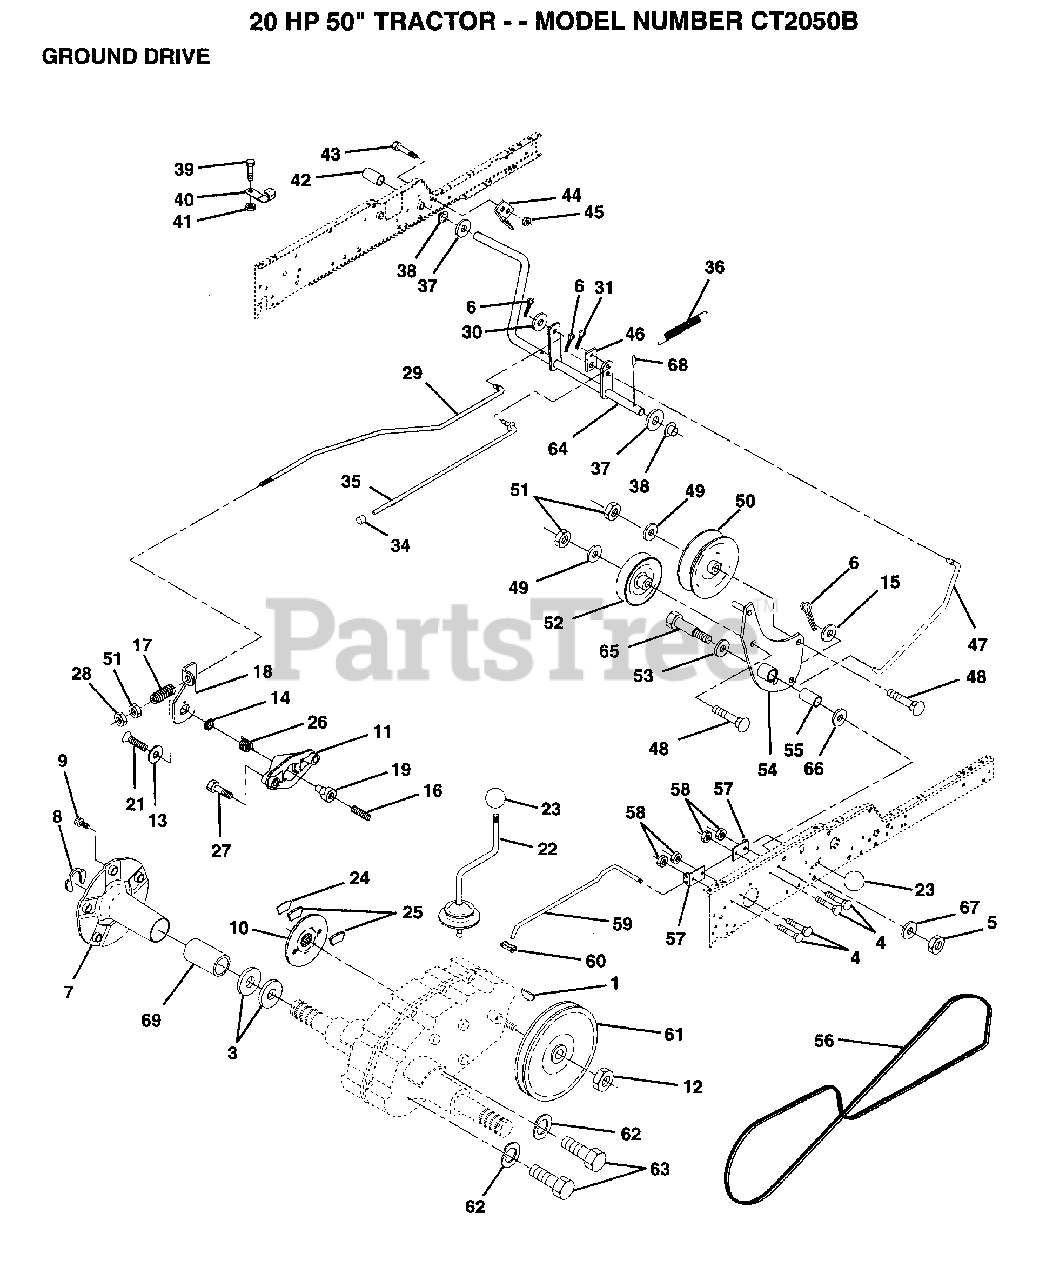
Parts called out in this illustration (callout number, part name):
3	WASHER T
4	BOLT
6	COTTER PIN
8	KLIP RING
9	BOLT.HUB.WHL.REAR
11	YOKE BRAKE DISC
12	NUT STD
13	WASHER SPECIAL
14	BUSHING LEVER BKT
15	WASHER
16	SCREW SET 1/4-20
17	"SPRING,ROD BRAKE"
18	LEVER BRAKE GT
19	CAM BRAKE DISC GT
21	SCREW FLT 1/4X28
22	GEAR SHFT LVR T
24	SUPPORT PUCK BRKE
25	PUCK BRAKE TOP
26	SPRING RET BRAKE
27	SCREW HX WASH
28	NUT
29	ROD BRAKE ZINC GT
30	WASHER
35	ROD BRAKE PART GT
37	WASHER
38	NYLINER T
39	SCREW
40	ACT-SWITCH T
42	PEDAL COVER T
43	BOLT LT
44	BRKT SWITCH GT
45	NUT
46	RETAINER SPRING
47	ROD.CLUTCH
48	BOLT
49	WASHER
50	FLAT IDLER PULLEY
51	NUT
52	PULLEY.IDLER.V.GR
53	WASHER T
54	ARM.ASM.IDLER.CLU
55	"LY, BEARING"
56	BELTV.GR.DR.83.
57	ROD BRACKET GT
58	NUT
59	ROD SHIFT HI LO
60	CONNECTING LINK
62	LOCKWASHER
63	BOLT
65	AXLE BOLT
66	WASHER.HARD.BLADE
67	WASHER
68	ROLL PIN STD
69	"COVER, HUB"
